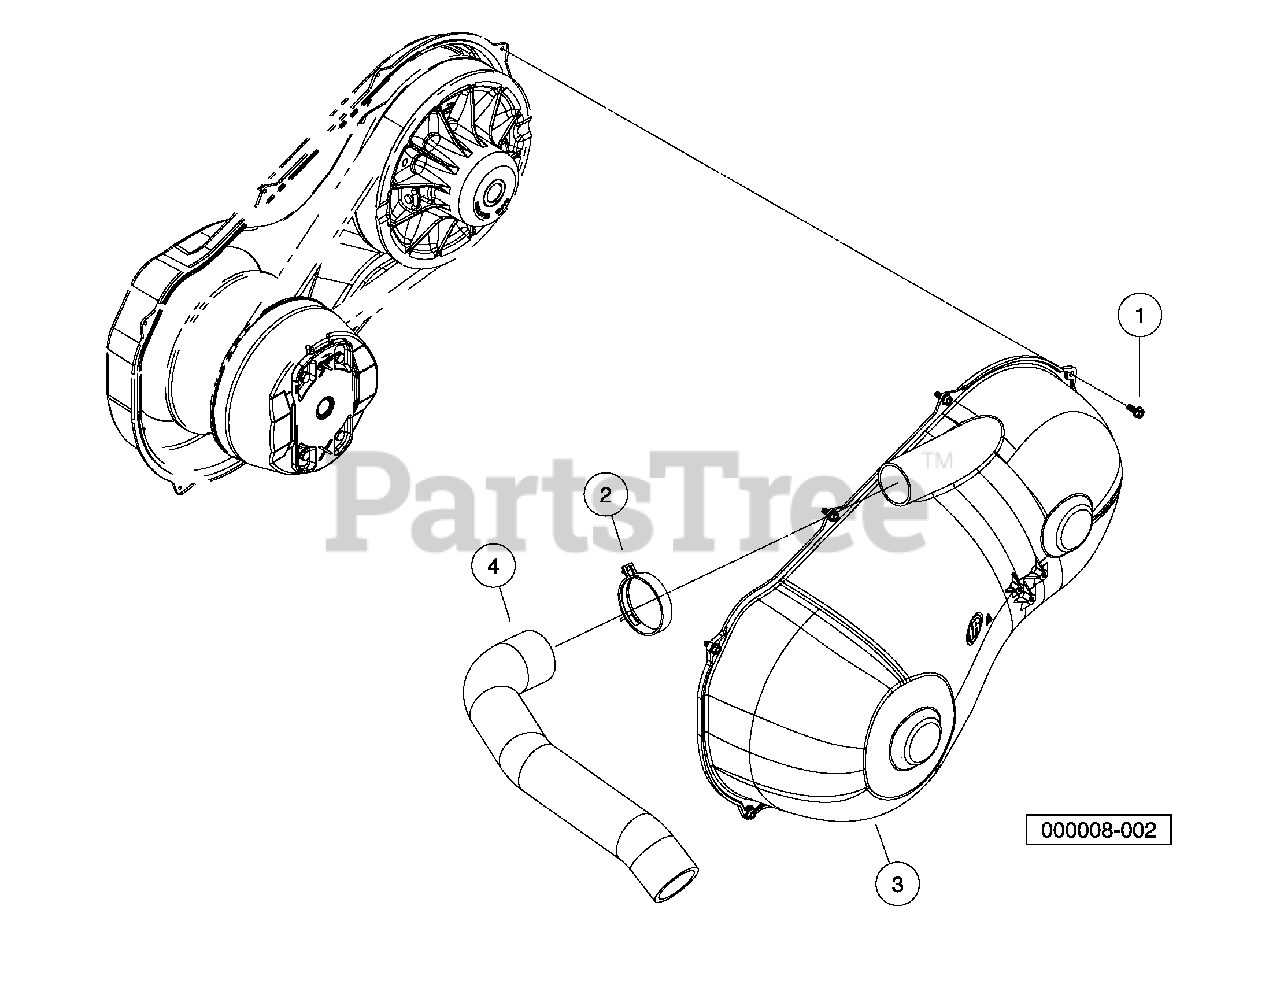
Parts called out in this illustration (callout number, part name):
1	Screw, M6 X 16 Tt Hx Fl Hd
2	Clamp, Hose, Ctb 64mm
3	Part Number for Club Car part number 102628301Cover, Cvt, Open
4	Hose, Outlet, Cvt
